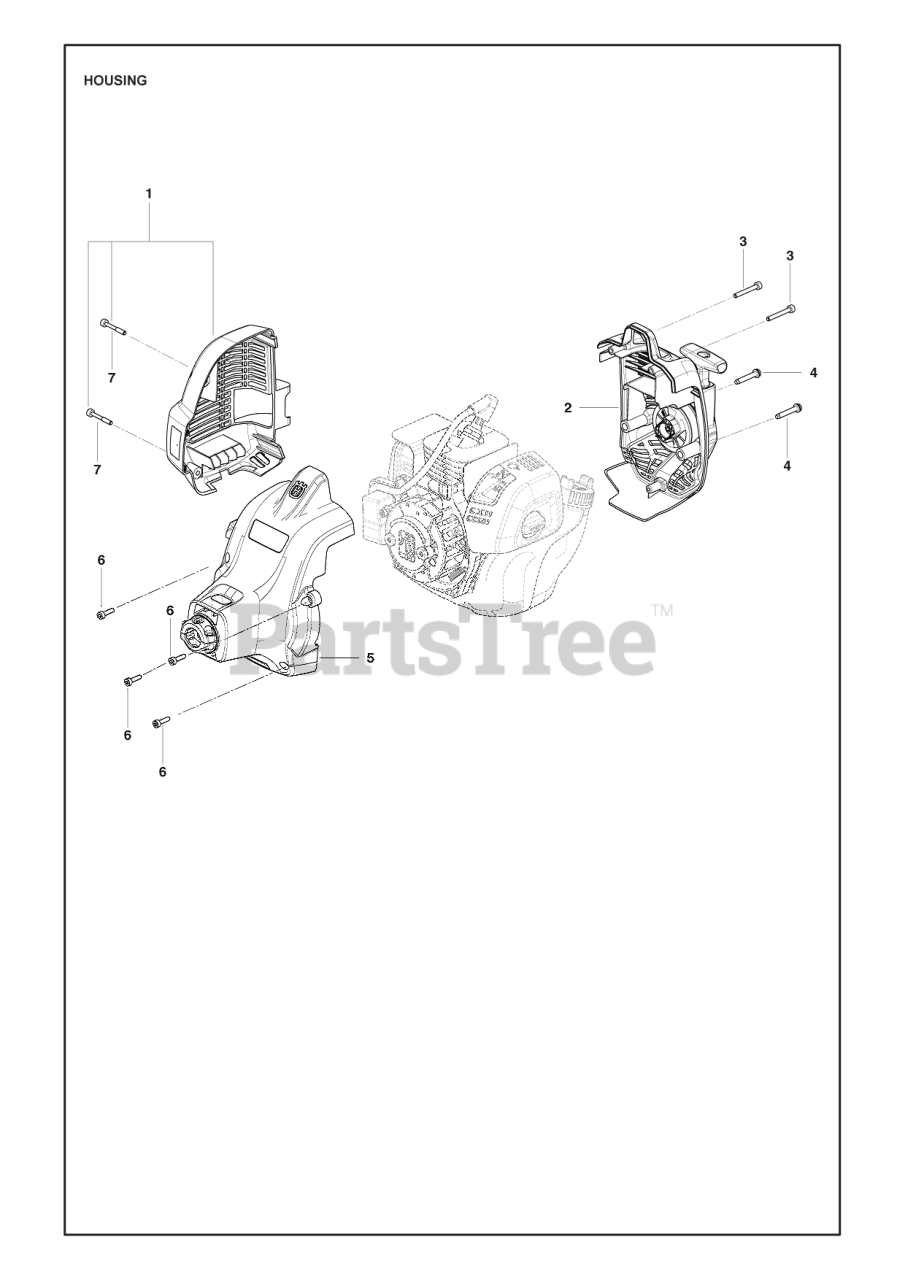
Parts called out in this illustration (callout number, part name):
1	SERVICE KIT 130 TRIMMER MUFFL
2	SERVICE KIT 130 TRIMMER START
4	SCREW M5-0.8X30MM
5	FAN HOUSING
6	SCREW M4 X .70 TT 16MM
